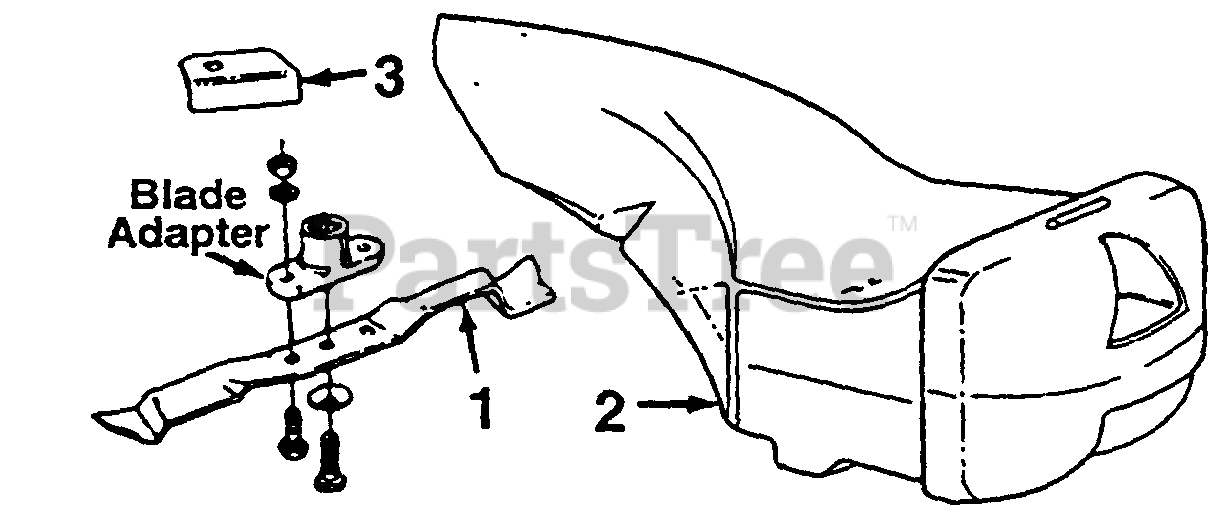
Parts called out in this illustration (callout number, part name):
1	Mulching Blade
2	Mulching Plug
3	Stop Bracket
